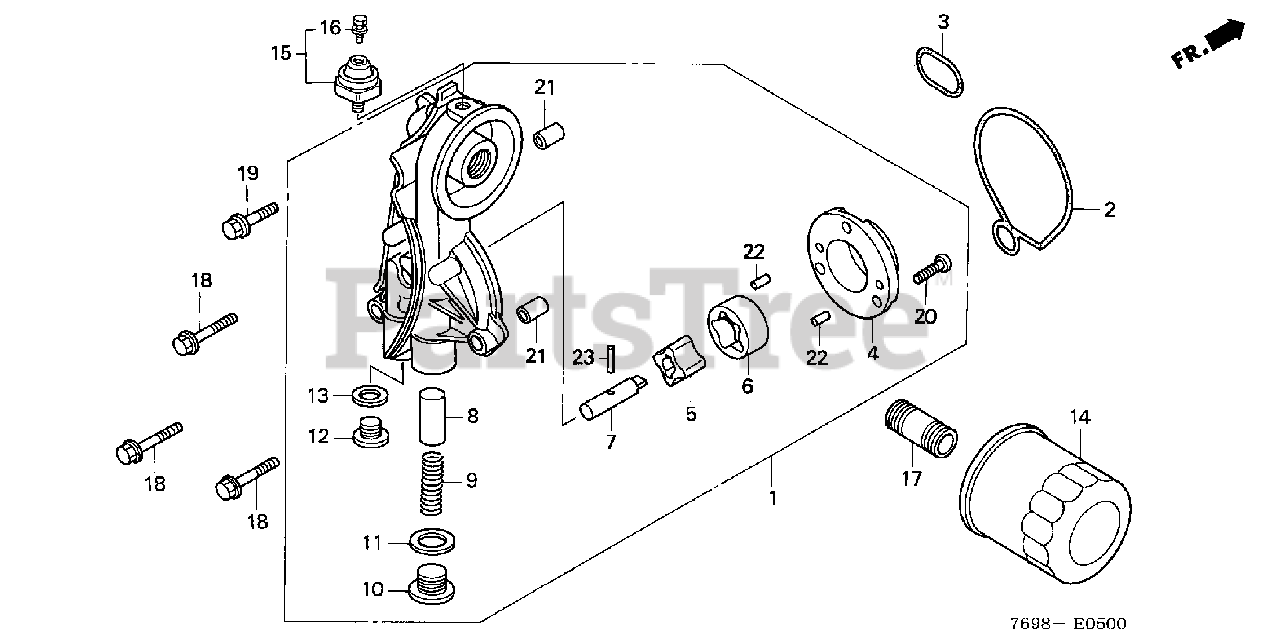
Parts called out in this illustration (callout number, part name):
1	PUMP ASSY., OIL
2	GASKET, OIL PUMP
3	GASKET, OIL PUMP (B)
4	COVER, OIL PUMP
5	ROTOR, OIL PUMP (INNER)
6	ROTOR, OIL PUMP (OUTER)
7	SHAFT, OIL PUMP
8	VALVE, RELIEF
9	SPRING, RELIEF VALVE
10	BOLT, SEALING (18MM)
11	WASHER, SEALING (18MM)
12	BOLT, SEALING (14MM)
13	WASHER, SEALING (14MM)
14	FILTER, OIL
14	FILTER, OIL (TOYO ROKI)
15	SWITCH, OIL PRESSURE
16	SCREW-WASHER (4X8)
17	HOLDER, OIL FILTER
18	BOLT, FLANGE (6X32)
19	BOLT, FLANGE (6X25)
20	SCREW, PAN (6X14)
21	PIN A, DOWEL (8X14)
22	PIN, DOWEL (5X8)
23	ROLLER (3X15.8)
